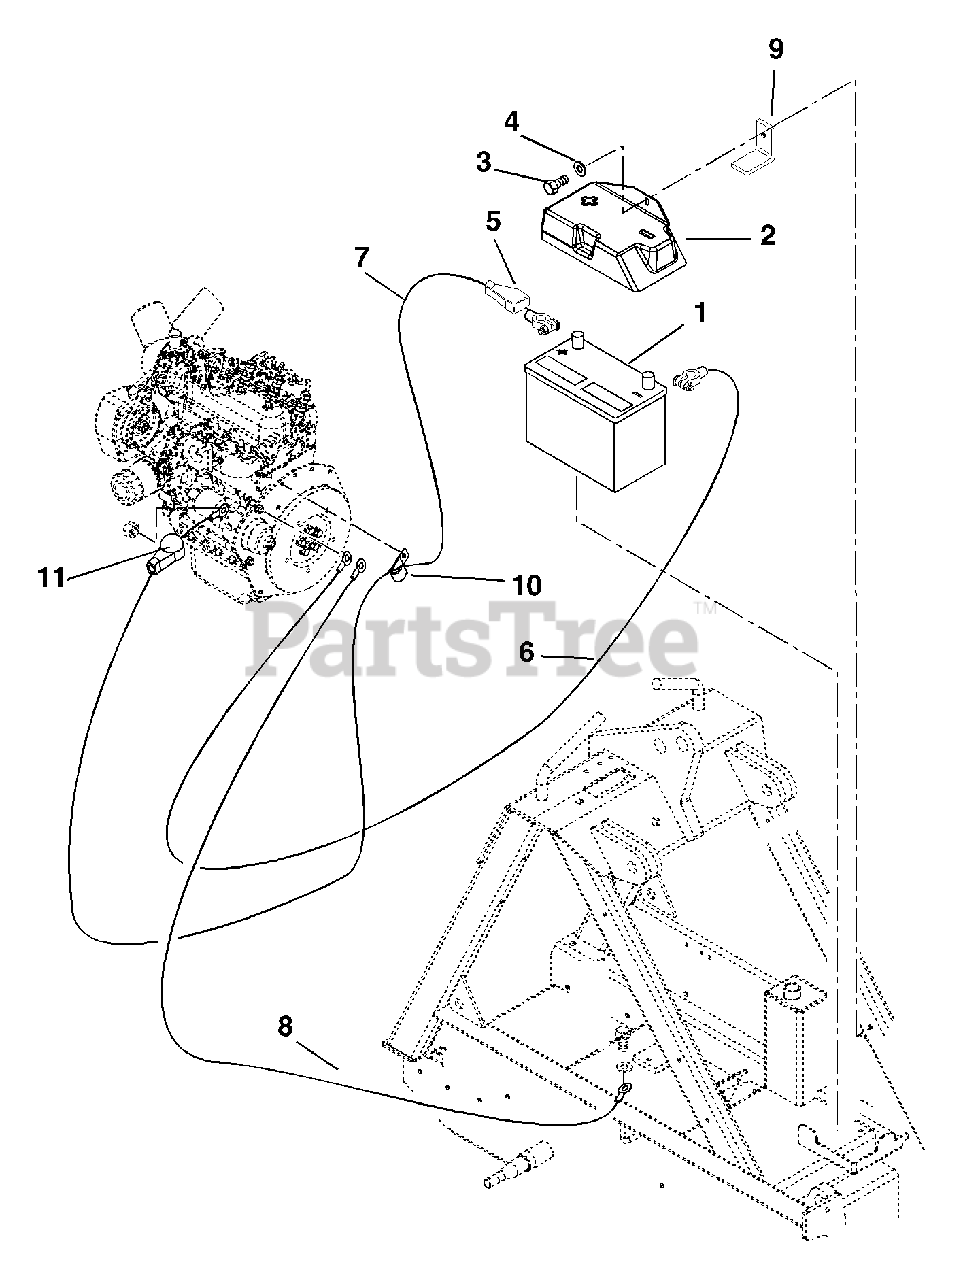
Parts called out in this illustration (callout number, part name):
2	Cover-Battery
3	Bolt-Hex M8 x 1.25 x 16
4	Washer-Flat-Steel .344 x .688 x .065
5	Cover,Battery Terminal
6	Cable-Battery Positive
7	Cable-Battery Negative
8	Wire-Ground
9	Bracket, Battery Holddown
10	J-Clamp
11	Battery Terminal Boot, Red
